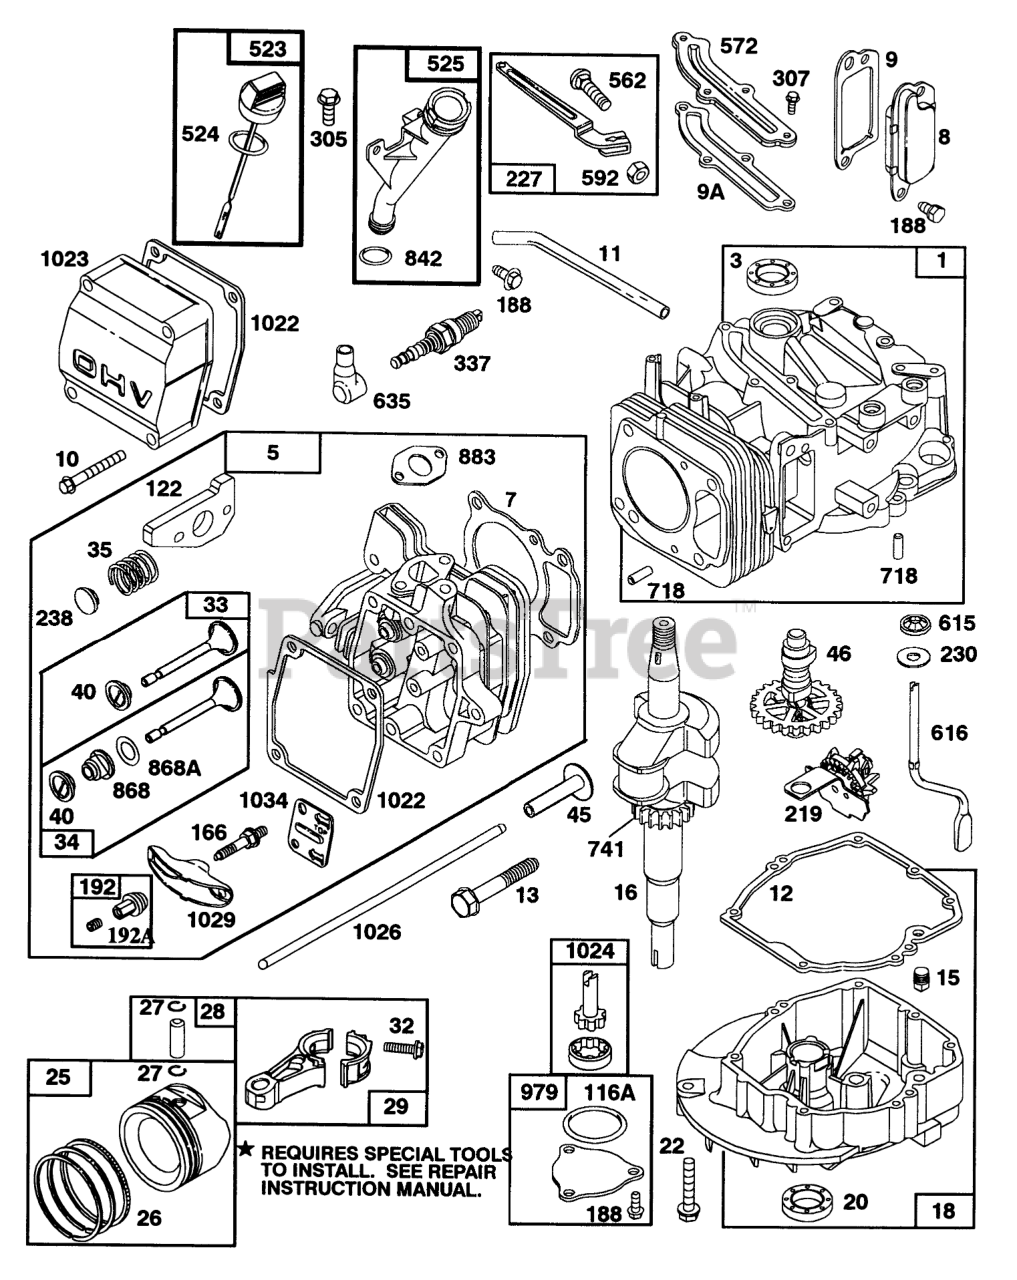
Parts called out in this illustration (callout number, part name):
1	CYLINDER ASSEMBLY
3	SEAL - OIL
5	CYLINDER HEAD
7	CYLINDER HEAD GASKET
8	Breather Assy
9	Gasket-Breather
9A	GASKET-BREATHER
10	HEX HEAD SCREW
11	BREATHER TUBE
12	ENGINE BASE GASKET
13	CYLINDER HEAD SCREW
15	PLUG - OIL DRAIN
16	CRANKSHAFT
18	ENGINE SUMP
20	SEAL-OIL
22	SCREW - ENGINE BASE
25	STD PISTON ASSEMBLY
26	STD RING SET
27	PISTON PIN LOCK
28	Pin Assy-Piston
29	CONNECTING ROD
32	Connecting Rod
33	EXHAUST VALVE
34	INTAKE VALVE
35	VALVE SPRING
40	SPRING RETAINER
45	VALVE TAPPET
46	CAM GEAR
116A	O RING SEAL
122	ADAPTER ASSEMBLY
166	ROCKER ARM STUD
188	SCREW - SEM
192	NUT - HEX SPECIAL
192A	Screw-Set
219	GOVERNOR/OIL SLINGER
227	GOVERNOR LEVER ASSEMBLY
230	WASHER
238	VALVE CAP
305	SCREW - HEX HEAD
307	SCREW - SEM
337	PLUG-SPARK
523	DIPSTICK-OIL
524	O-RING
525	OIL FILLER TUBE
562	GOVERNOR LEVER BOLT
572	BAFFLE - CYCLINDER
592	HEX NUT
615	FASTENER
616	GOVERNOR CRANK
635	SPARK PLUG ELBOW
718	DOWEL - SLEEVE
741	TIMING GEAR
842	O-RING
868	SealAssy-Valve
868A	Seal-Valve
883	EXHAUST GASKET
979	OIL PUMP COVER
1022	ROCKER COVER GASKET
1023	Cover-Valve
1024	OIL PUMP
1026	PUSH ROD
1029	ROCKER ARM
1034	PUSH ROD GUIDE
